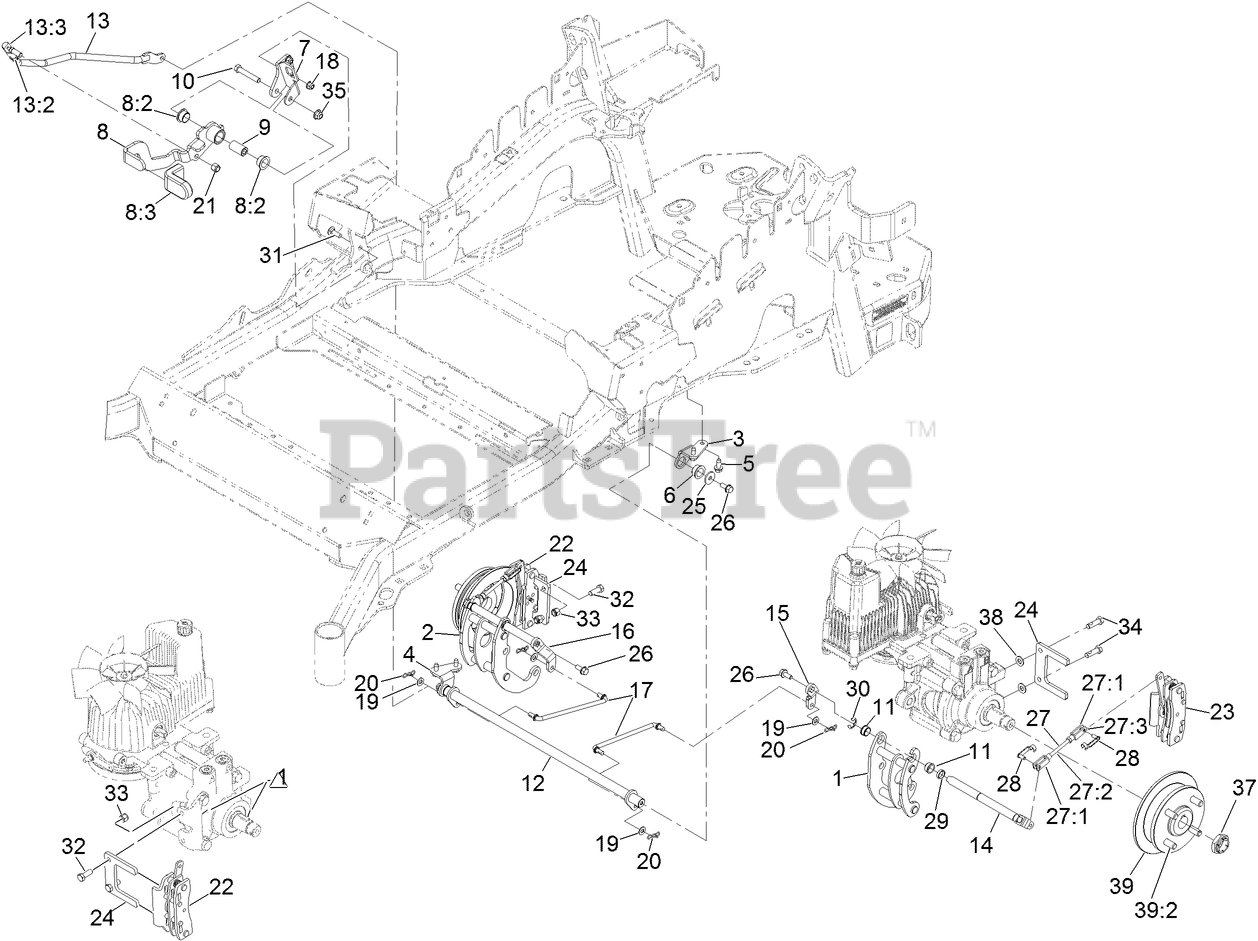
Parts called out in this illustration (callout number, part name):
1	MOUNT-BELLCRANK, LH
2	MOUNT-BELLCRANK, RH
3	MOUNT-PIVOT, LH
4	MOUNT-PIVOT, RH
5	SCREW-HWHTF
6	BUSHING-FLANGE
7	BRACKET-MOUNT
8	BRAKE LEVER ASM W/GRIP M-R
8:2	BUSHING-FLANGE
8:3	GRIP-LEVER
9	HANDLE-PIVOT, BRAKE
10	SCREW-HH
11	BUSHING
12	SHAFT-CROSS
13	ASM, FRONT LINKAGE
13:2	END-TIE ROD, RH
13:3	NUT-HJ
14	BELLCRANK
15	ARM-INNER, RH
16	ARM-INNER, LH
17	WIREFORM, MID-LINK, LWB
18	NUT-HF, NI
19	WASHER-PLAIN
20	PIN-COTTER, LOCKING
21	NUT-LOCK
22	CALIPER-BRAKE, RH
23	CALIPER-BRAKE, LH
24	PLATE-MOUNT, BRAKE
25	WASHER-FLAT
26	SCREW-HHF
27	REAR LINKAGE ASM
27:2	LINKAGE, REAR
27:3	NUT-JAM
28	PIN-CLEVIS, SPRING
29	SPACER
30	E-RING
31	BOLT-CARR
32	SCREW-HH,
33	NUT-LOCK
34	SCREW-HH, PATCH,
35	NUT-HF, NI
37	LOCKNUT
38	WASHER-FLAT
39	WHEEL HUB ASM
39:2	STUD-WHEEL
